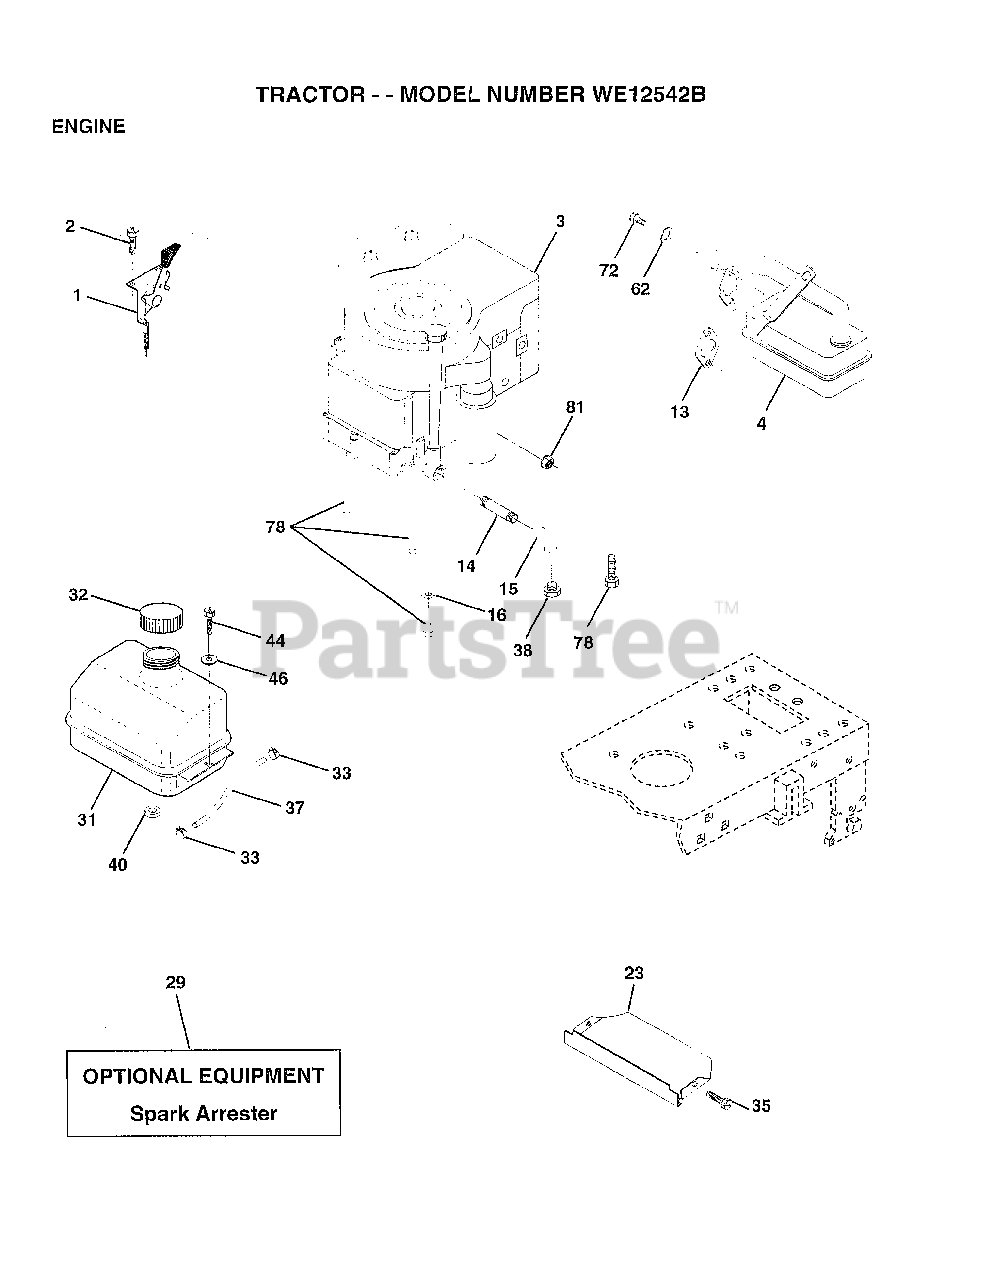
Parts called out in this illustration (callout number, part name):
1	CONTROL THROTTLE
2	SCREW LT
4	MUFFLER
13	GASKET ENG 1 313 LD TIN PLATED
14	PIPE NIPPLE
15	ELBOW
16	LOCKWASHER
23	SHIELD.BRN/DBR.GD
31	TANK.FUEL.LT.
32	CAP ASM FUEL
33	HOSE CLAMP
35	SCREW
37	LINE FUEL
44	SCREW HEX CRT
46	WASHER
62	LOCKWASHER
72	SCREW
78	SCREW
81	NUT
